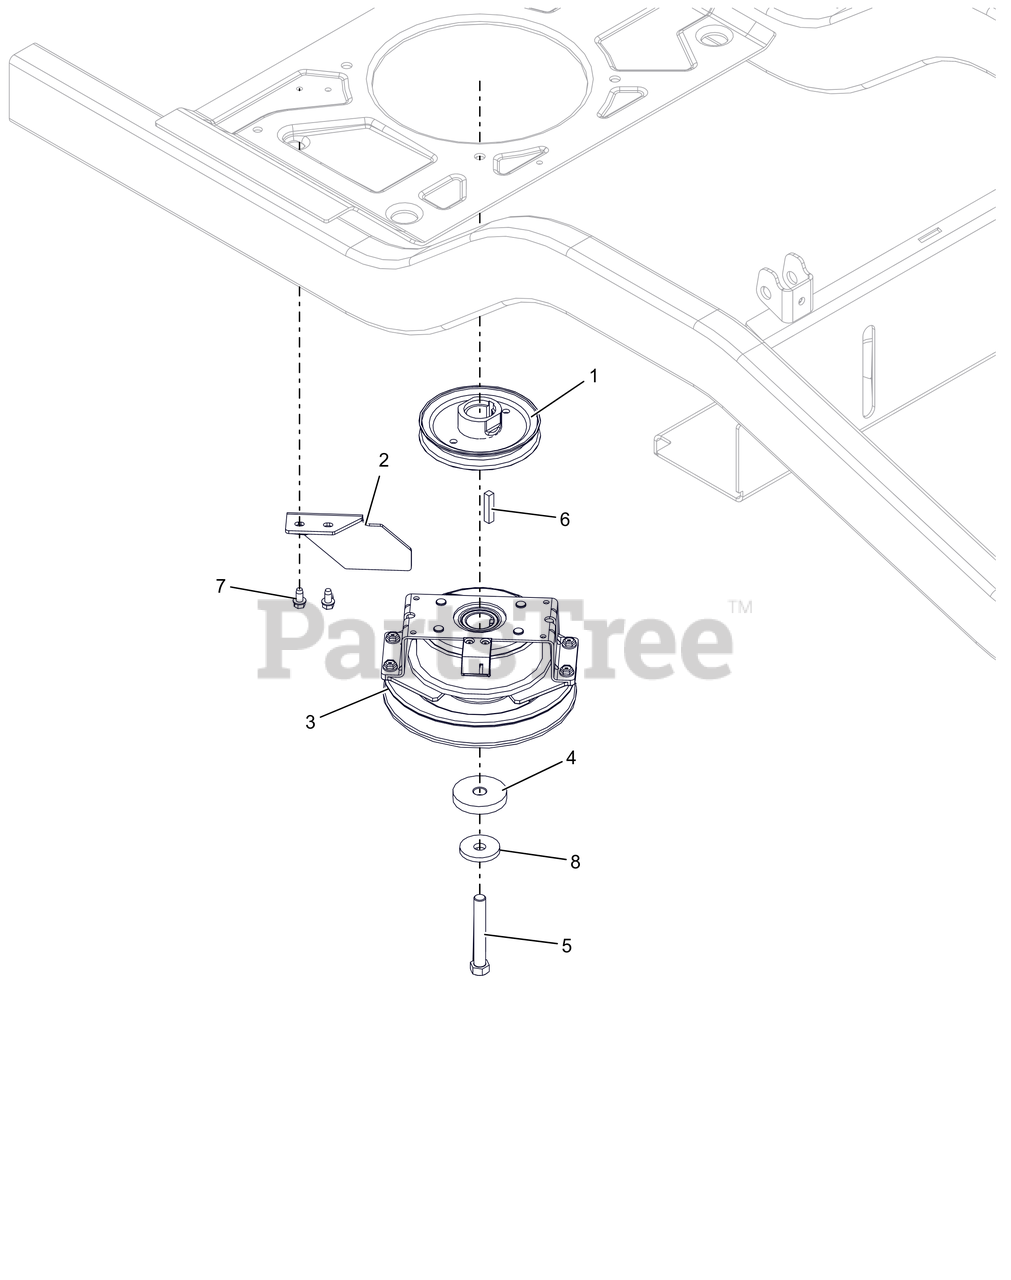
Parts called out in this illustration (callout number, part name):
1	WLDMT,PULLEY-4.50ODX1.003
2	BRKT, CLUTCH STOP HD
3	CLUTCH, OGURA DBL SPRG
4	SPACER, .474/.459X2.00X.350
5	BLT, HEX 0.4375-20X3 G8 ZCC NT
6	KEY-SQ .25 X 1.25 X .25 SAE
7	SCR-TAP .25-20X.50 HWH ZCC
8	WASHER, 7/16" SPRING DISK
